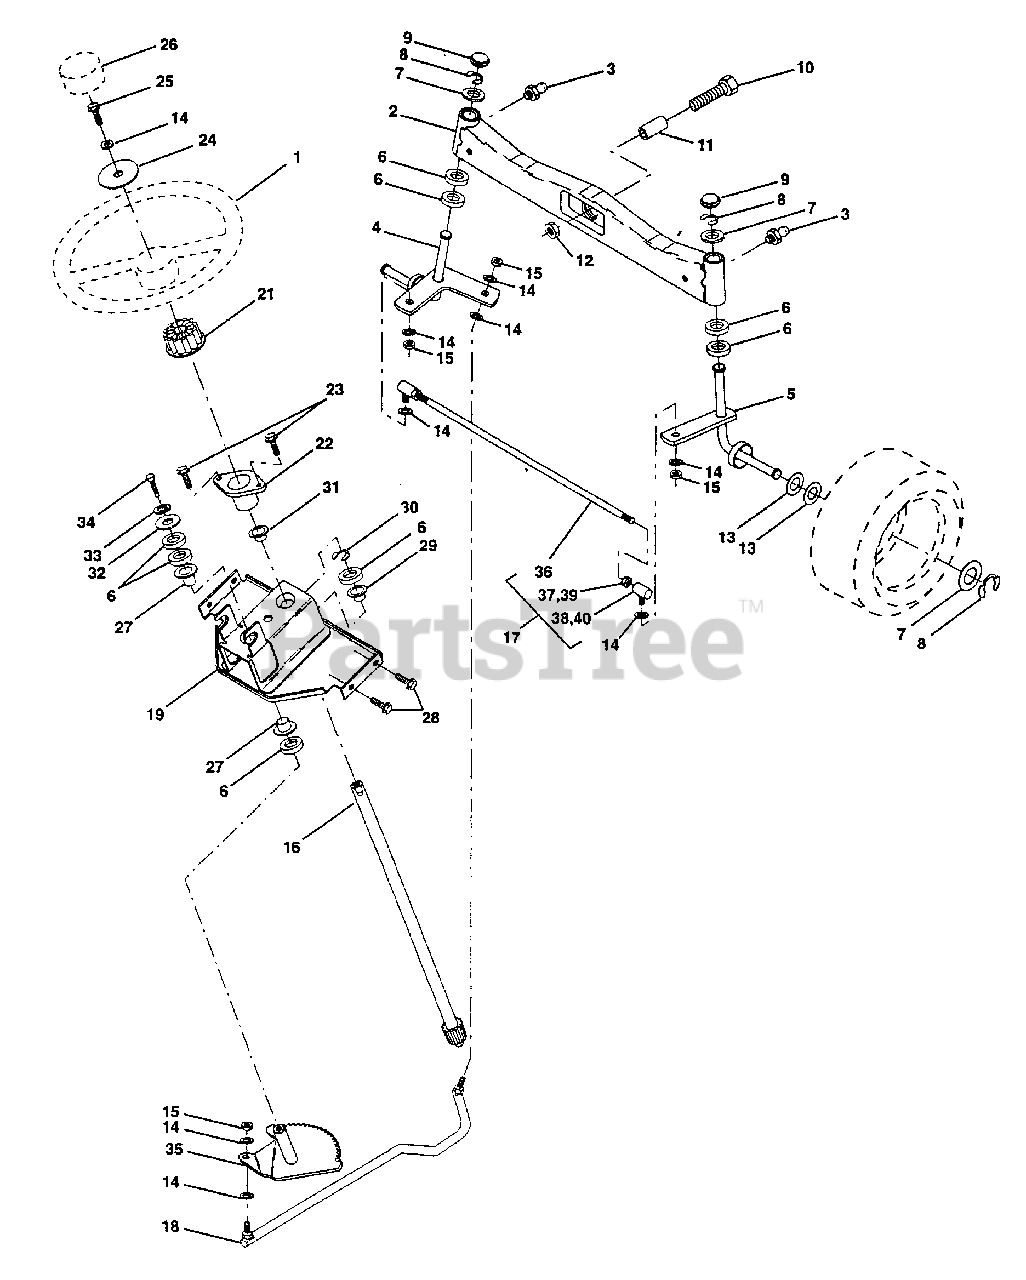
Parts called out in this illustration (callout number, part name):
3	ZERK M
4	SPINDLE.ASM.LH
6	WASHER .T
7	WASHER
8	RING
9	CAP
10	BOLT
11	SPACER BEARING
12	"NUT-LOC,FLANGE LT"
13	WASHER
14	LOCKWASHER
16	SHAFT.STEER.VGT
17	ROD.ASM.TIE.BALL
18	DRAGLINK.BALL.JOI
21	ADAPTER LT
24	WASHER T
25	BOLT
26	ST WHL INSERT CAP
27	COL. SRTG. BEAR.
28	SCREW
29	"FLANGE GT, BEAR."
30	KLIP RING
31	BUSHING.NYLINER.
32	WASHER
33	LOCKWASHER
34	BOLT
35	GEAR.ASM.SECTOR.
37	NUT
38	JOINT.RH
39	NUT
40	JOINT.LH
